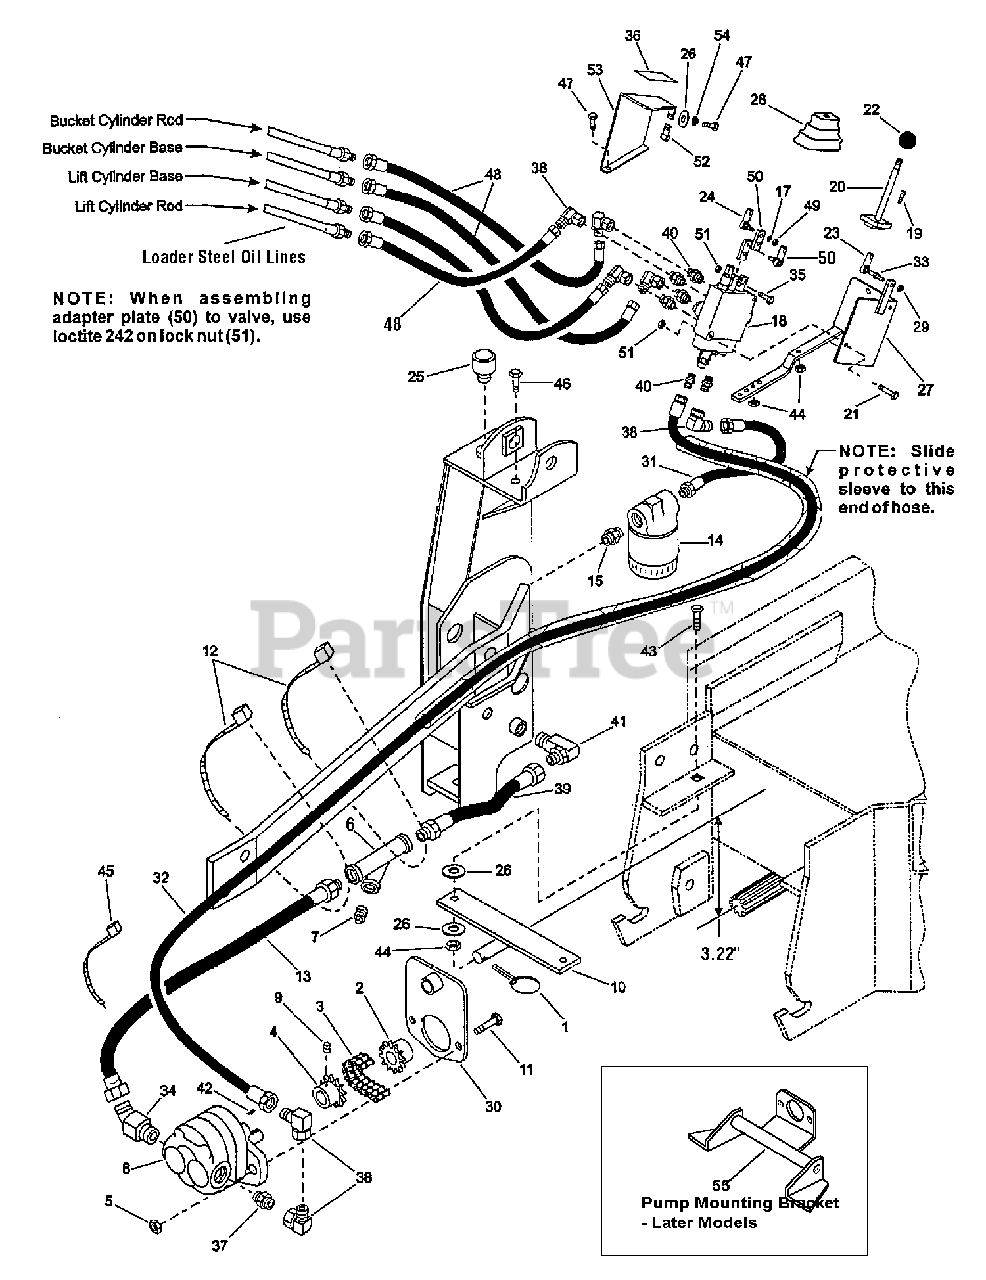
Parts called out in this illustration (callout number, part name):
1	PIN, Klik, 3/16 x 1-5/8
2	SPROCKET, w/ Spline Hub
3	CHAIN, Roller, #40-2 x 12 Pitches
4	SPROCKET, w/ Keyway Hub
5	LOCKNUT, Hex, 3/8-16
7	PLUG, Pipe, 3/8 NPT
8	PUMP ASSEMBLY (See SERVICE PARTS - Hydraulic Gear Pump)
9	SETSCREW, Socket Head, 1/4-20 x 1/4, G8
10	BRACKET, Pin Assembly
11	CAPSCREW, Hex Head, 3/8-16 x 1-1/4
12	TIE, Self-Locking
13	TUBE, 1/2 x 28, Suction
14	FILTER ASSEMBLY
15	FITTING, Adapter, 3/8 x 3/8
16	NUT, Hex, 1/4-20
17	LOCKWASHER, 1/4
18	VALVE ASSEMBLY(See SERVICE PARTS - Hydraulic Valve Assembly)
19	CAPSCREW, Hex Socket Head, 1/4-28 x 3/4
21	CAPSCREW, Hex Head,1/4-20 x 2
23	BALL JOINT, Female
24	BALL JOINT, Male
25	CAP, Breather
26	WASHER, 5/16
27	BRACKET, Valve Mounting
29	NUT, Hex, 1/4-28
30	BRACKET, Pump Mounting
31	HOSE, Hydraulic, 3/8 x 11 (valve to filter)
32	HOSE, Hydraulic, 3/8 x 63 (pressure)
33	STUD, Ball Joint
34	FITTING, 7/8 O-Ring x 7/8 JIC, 45 Degree (outlet port on pump)
35	CAPSCREW, Hex Head, 1/4-20 x 3/4
36	DECAL, Single Handle
37	FITTING, 3/4 O-Ring x 9/16 JIC
38	FITTING, 9/16 JIC x 91/6 JIC, 90 Degree (between outlet fitting pump & hose)
39	HOSE, Hydraulic, 1/2 x 16
40	FITTING, 9/16 O-Ring x 9/16 JCI
41	FITTING 3/4 JIC x 1/2 NPTF, 90 Degree
43	CARRIAGE BOLT, 5/16-18 x 1
44	LOCKNUT, Hex, 5/16-18
45	TIE, Self Locking
46	CAPSCREW, Hex Head, 5/16-18 x 1-1/4
47	CAPSCREW, Hex Head, 5/16-18 X 1
48	HOSE, Hydraulic, 3/8 x 24
49	NUT, Hex, 1/4-28
50	ADAPTER PLATE
51	LOCKNUT, Hex,1/4-20
54	LOCKWASHER, Lock, 5/16
55	BRACKET, Pump Mounting (Replaces Ref. Nos. 1, 10, 26, 30, 43, & 44) in Later Models
